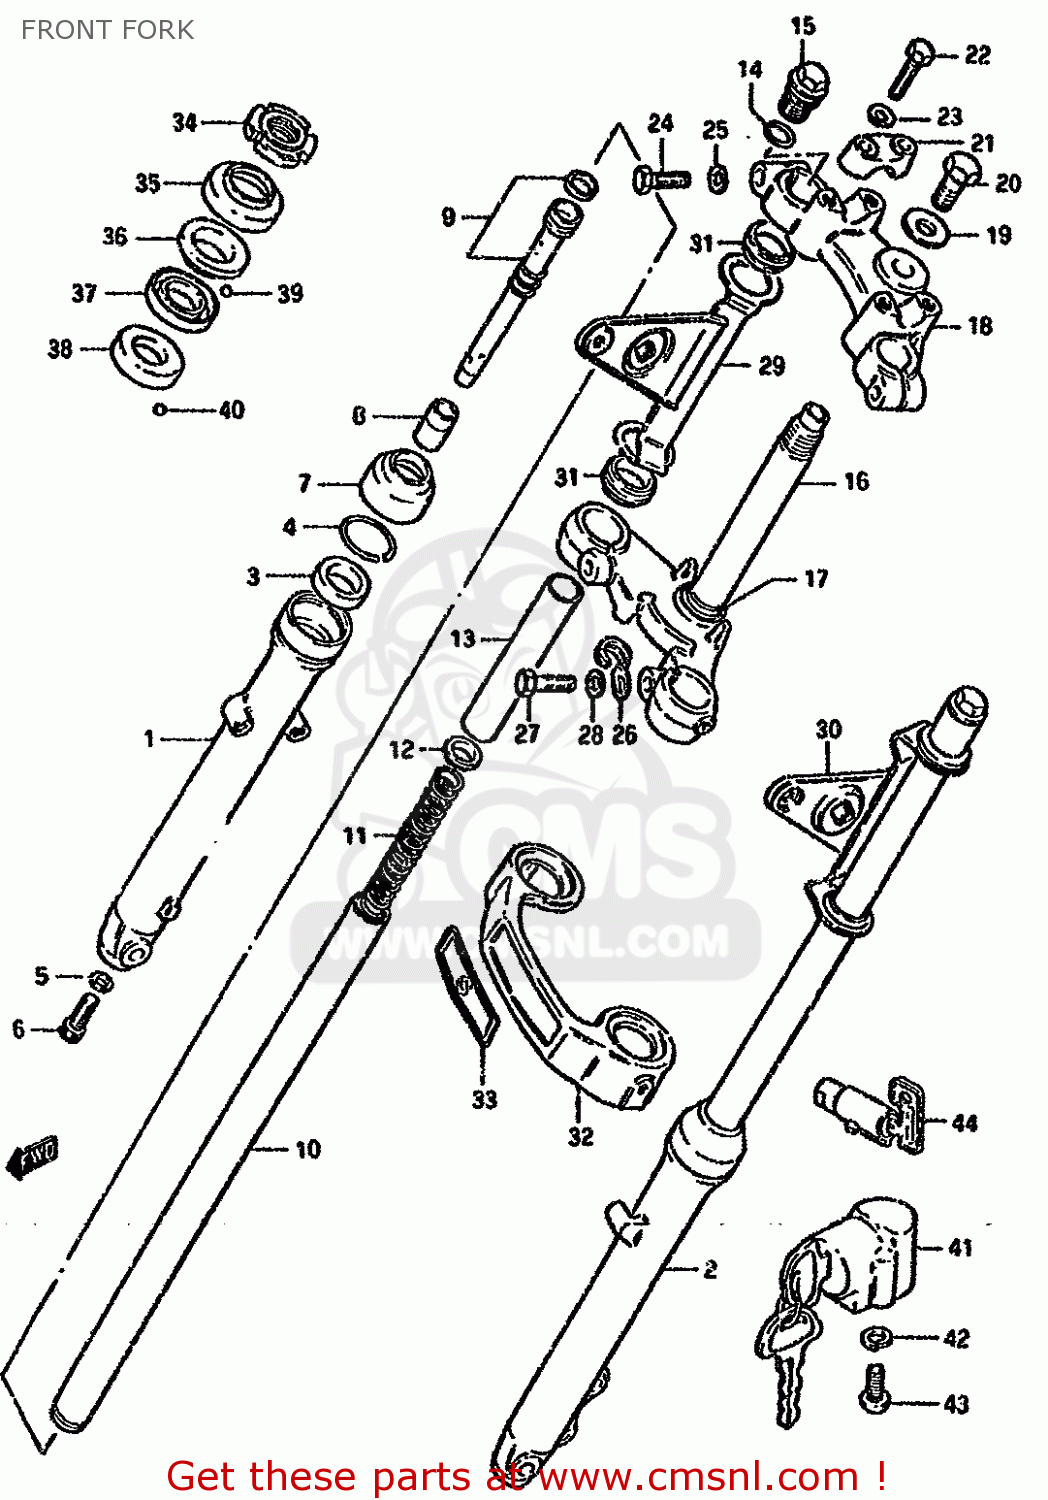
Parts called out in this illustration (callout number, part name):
1	TUBE,OUTER,R
2	TUBE,OUTER,L
3	SEAL,OIL
4	RING,SNAP
5	GASKET (NAS)
6	BOLT,FORK CYLINDER(10X25)
7	SEAL,DUST
8	PIECE,OIL LOCK
9	CYLINDER
10	TUBE,INNER
11	SPRING
12	GUIDE,SPRING COVER
13	SPACER
14	O RING
15	CAP
16	STEM,STEERING
17	RACE,STEERING OUTER LWR
18	HEAD,STEERING STEM(BLACK)
19	WASHER,STEM HEAD(10.5X30X3.2)
20	BOLT,FORK INNER TUBE
21	HOLDER,HANDLE(BLACK)
22	BOLT
23	LOCK WASHER
24	BOLT,FORK INNER TUBE F
25	WASHER,LOCK,10
26	CLIP
27	BOLT,FR FORK LWR(12X33)
28	WASHER,LOCK 12
29	BRACKET,HEADLAMP,R
30	BRACKET,HEADLAMP,L
31	CUSHION,HEADLAMP BRACKET
32	COVER,FR FORK
33	EMBLEM,FR FORK COVER
34	NUT,STEERING STEM(25X44X10)
35	DUST SEAL,STEERING UPR
36	RACE,STEERING OUTER UPR
37	RACE,STEERING INNER UPR
38	LACE,STEERING INNER LWR
39	BALL
40	BALL
41	LOCK ASSY,STEERING
42	LOCK WASHER
43	SCREW
44	LOCK ASSY,STEERING(NEIMAN)
